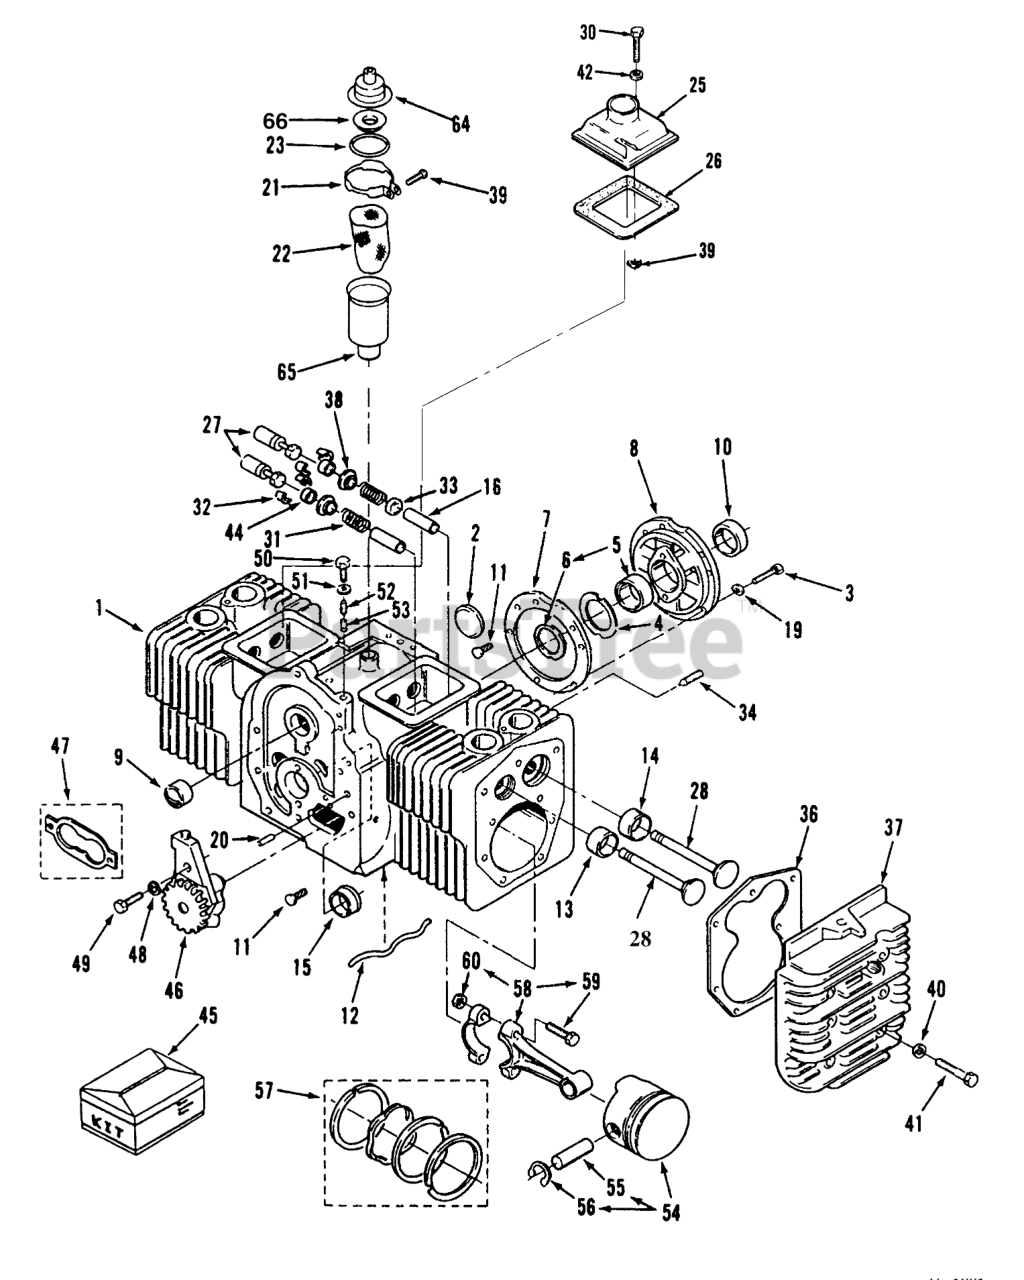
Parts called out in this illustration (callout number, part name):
1	CYLINDER BLOCK
3	HEX HD CAPSCREW
5	BEARING KIT (STANDARD SLEEVE)
6	WASHER
7	GASKET
8	PLATE-BEARING, REAR
9	SLEEVE-BEARING
11	PIN-DRIVE
12	OIL TUBE
13	STD INSERT
14	STD INSERT
15	KIT-BEARING, SLEEVE
16	Guide-ExhaustValve
19	WASHER-LOCK
20	PIN-GEAR COVER
21	Clamp
22	FILTER
23	SEAL - O-RING
25	VALVE-COVER L.H.
26	GASKET
27	TAPPET
28	INTAKE VALVE
30	HHCS 1/4-20 X 1 3/4
31	Spring
32	VALVE SPRING LOCK
33	VALVE STEM SEAL
34	SCREW-SET
36	GASKET
37	CYL RS HEAD
38	Washer
39	SCREW-TAPPING, ROUND HEAD
40	WASHER
41	Screw-HH
42	WASHER
44	VALVE CAP
45	ENGINE GASKET KIT
47	GASKET KIT
48	WASHER-FLAT
49	SCREW - CAP HEX HEAD
50	SCREW-HH
51	WASHER
52	SPRING
53	PLUNGER
54	STD PISTON KIT
55	Piston Pin
56	Piston Pin
57	RING/PISTON KIT
58	CONNECTING ROD W/NUT
64	BREATHER-CAP AND VALVE
65	TUBE-BREATHER
66	SCREEN-BREATHER TUBE
